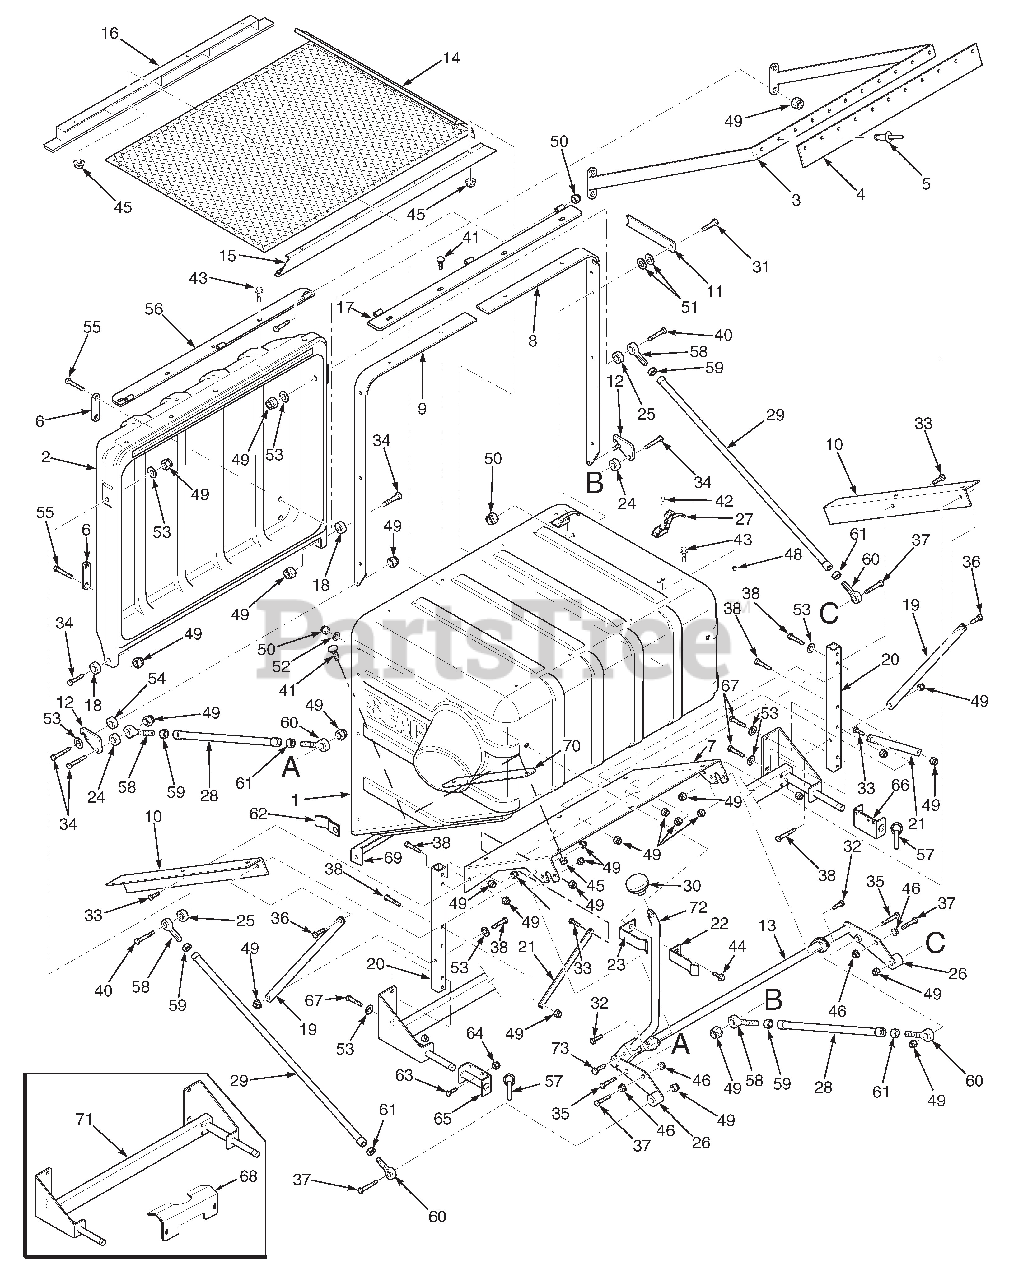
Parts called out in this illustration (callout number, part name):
1	Hopper, GC-STT-CS
2	Door, GC-CS
3	Sweeper Weldment, GC-CS
4	Pad, Rubber
5	Pop Rivet, 3/16 x .652
6	Plate, Stiffener
7	Support Frame, Hopper
8	Hinge Bracket, LH
9	Hinge Bracket, RH
10	Bracket, Hopper Support
11	Latch, Door Prop
12	Plate, Latch
13	Bellcrank Weldment, Lever
14	Debris Screen Weldment
15	Screen Support Weldment, Rear
16	Screen Support Weldment, Front
17	Hinge Weldment, Hopper
18	Spacer
19	Brace Stiffener, Short
20	Tube, Upright
21	Brace, Engine Mount
22	Latch, Dump Rod Inner
23	Latch, Dump Rod Outer
24	Spacer
25	Spacer
26	Spacer
27	Latch, Hood
28	Linkage Assembly, Lower
29	Linkage Assembly, Upper
31	Bolt, Hex Head 5/16-18 x 1-1/4"
32	Bolt, Hex Head 3/8-16 x 3/4"
33	Bolt, Hex Head 3/8-16 x 1"
34	Bolt, Hex Head 3/8-16 x 1-1/2"
35	Bolt, Hex Head 3/8-16 x 1-3/4"
36	Bolt, Hex Head 3/8-16 x 1-1/4"
37	Bolt, Hex Head 3/8-16 x 2"
38	Bolt, Hex Head 3/8-16 x 2-1/4"
39	Bolt, Hex Head 5/16-18 x 3-1/2"
40	Bolt, Hex Head 3/8-16 x 3-1/2"
41	Bolt, Carriage 5/16-18 x 1"
42	Screw, #10-32 x 1/2"
43	Cap Screw, 5/16-18 x 3/4" Serr. Flan.
44	Cap Screw, 5/16-18 x 1" Serr. Flan.
45	Nut, 5/16-18 Serrated Flange
46	Nut, 3/8-16 Serrated Flange
47	Nut, 3/8-16 UNC Jam
48	Nut, #10-32 Elastic Stop
49	Nut, 3/8-16 Elastic Stop
50	Nut, 5/16-18 Elastic Stop
51	Washer, Special Wave
52	Washer, 5/16-.375 x .875 x .083 Flat
53	Washer, 3/8-.931 x .938 x .105 Flat
54	Bushing, Hopper Latch GC-CS
55	Bolt, Hex Head 3/8-16 x 3"
56	Hinge Weldment, Door
58	Rod End Male, 3/8-24 LH Thread
59	Nut, 3/8-24 UNF LH Thread
60	Rod End Male, 3/8-24 RH Thread
61	Nut, 3/8-24 UNF RH Thread
62	Alignment Bracket, GC-CS
63	Bolt, Hex Head 3/8-16 x 1"
64	Nut, 3/8-16 Elastic Stop
65	Hitch Bracket Weldment
66	Hitch Bracket Weldment, Floating
67	Bolt, Hex Head 3/8-16 x 3-3/4"
68	Support Bracket, Catcher
69	Bracket, Lower Stiffener
70	Retainer Strip, Hopper
71	Frame Weldment
72	Rod, Dump Lever
73	Bolt, Hex Head 5/16-18 x 1-3/4"
